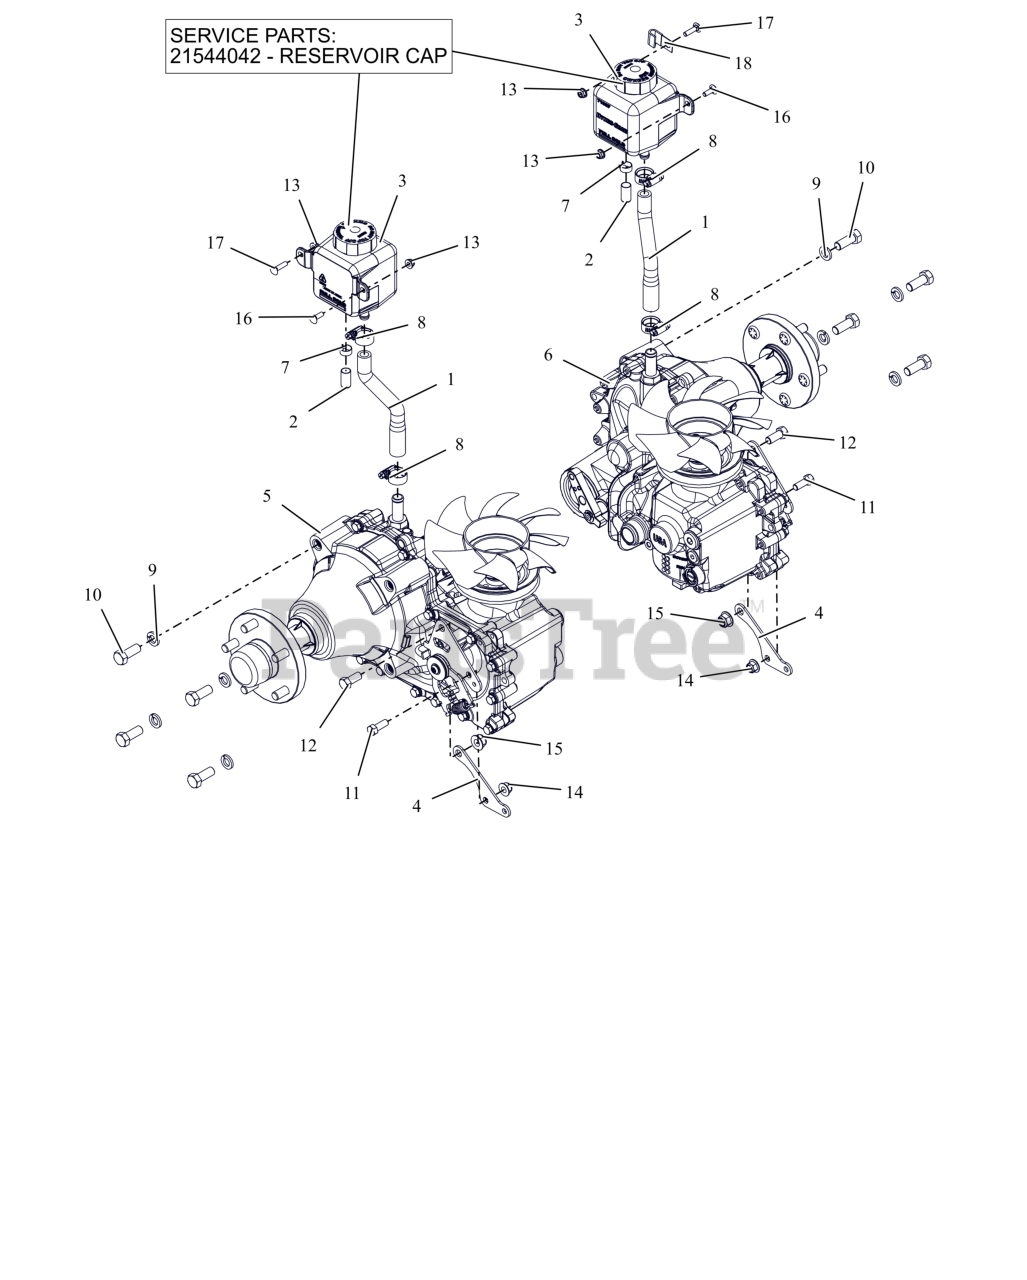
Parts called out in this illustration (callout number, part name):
1	HOSE,PT200/400 TRANS OVERFLOW
2	CAP, .50 BARBED FITTING
3	TANK, HYDRO OVERFLOW 700 ML
3	CAP, HYDRO RESERVOIR REPLAC.
4	DRV CNTRL LINKAGE MTG BRKT-BLK
5	TRANSAXLE, RH HG ZT-5400
6	TRANSAXLE, LH HG ZT-5400
7	CLAMP, .62 SPRING
8	CLAMP,.88 DIA. HOSE
9	WSHR,LK-REG .500X.125 ZCC
10	BLT,HEX .50-13X1.25 G5 ZCC
11	BLT,HEX .38-16X1.00 G5 ZCC
12	BLT, HEX 0.4375-14X1 GR5 ZCC
13	NUT,NYL-FLG .25-20 GF ZCC
14	NUT,NYL-FLG .38-16 GF ZCC
15	NUT,NYL-FLG .44-14 GF ZCC
16	BLT, RHSN .25-20X.750 G5 ZCC
17	BLT, RHSN .25-20X1.00 G5 ZCC
